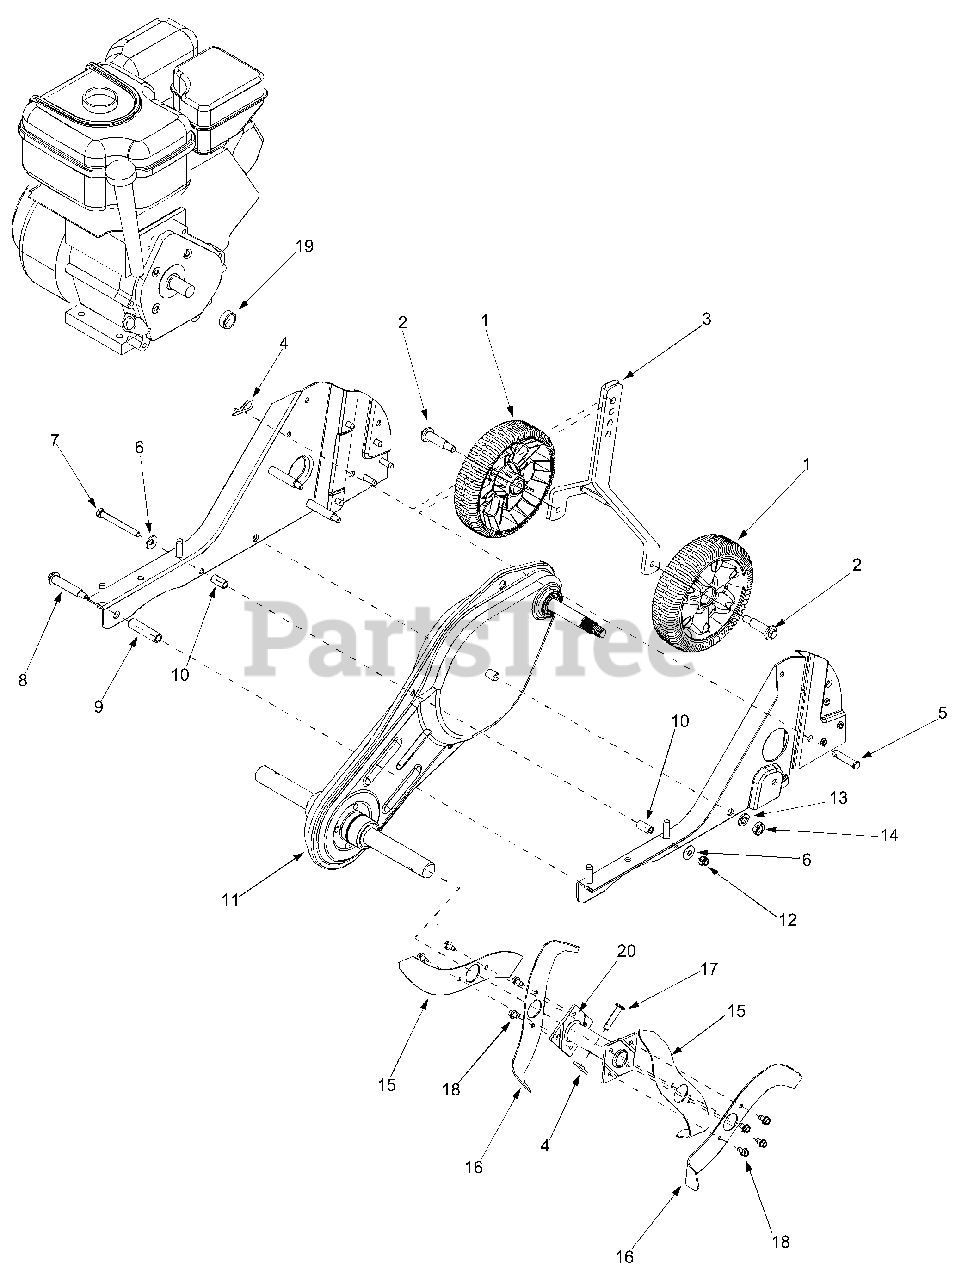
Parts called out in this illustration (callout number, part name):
1	Wheel 7 x 1.8
2	Shoulder Screw
4	Cotter Pin
5	Clevis Pin
6	Bell Washer .340 ID x .872 OD
7	Hex Cap Screw 5/16-18 x 3.0
8	Shoulder Screw
9	Spacer .51 ID x .69 OD x 1.97Lg
10	Spacer .47 OD x .96Lg
11	Chain Case Assembly
12	Hex Lock Nut 5/16-18
13	Lock Washer 7/16
14	Jam Nut 7/16-20
18	Hex Washer Screw 1/4-20 x .50
19	Spacer .790 ID x .347 Lg
